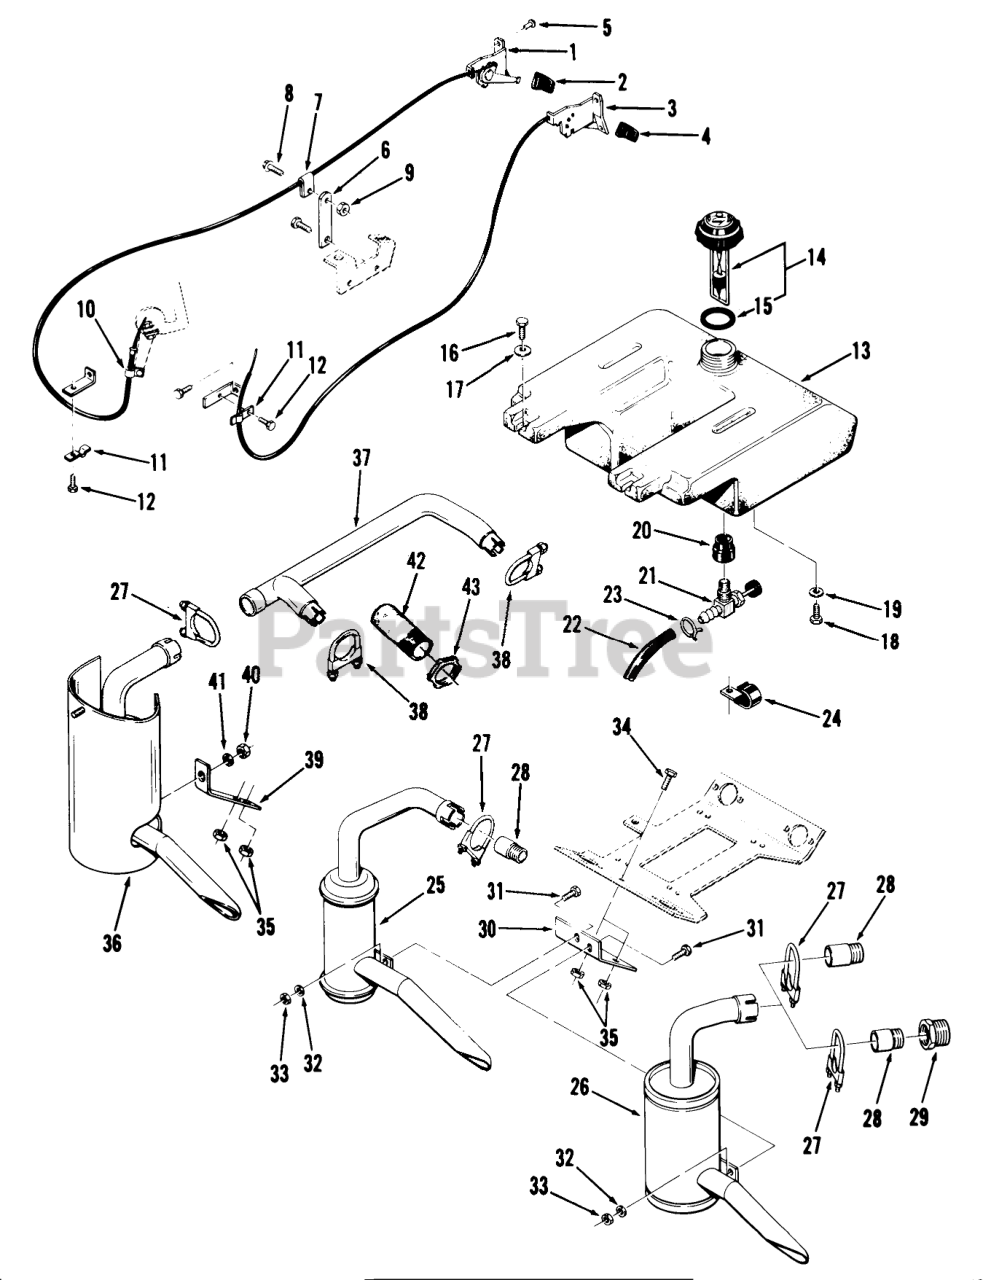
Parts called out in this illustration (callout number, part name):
1	THROTTLE CONTROL
2	KNOB-THROTTLE
3	CONTROL-CHOKE
4	KNOB-CHOKE
5	RIVET-4
7	THROTTLE CONTROL CLP
11	CLAMP-CABLE
13	TANK-FUEL
14	ASSY-GAUGE CAP
21	VALVE-FUEL
24	CLIP
25	ASSY-MUFFLER
26	MUFFLER ASSEMBLY
27	ASSY-MUFFLER CLAMP
28	NIPPLE- 1X2 SPECIAL
